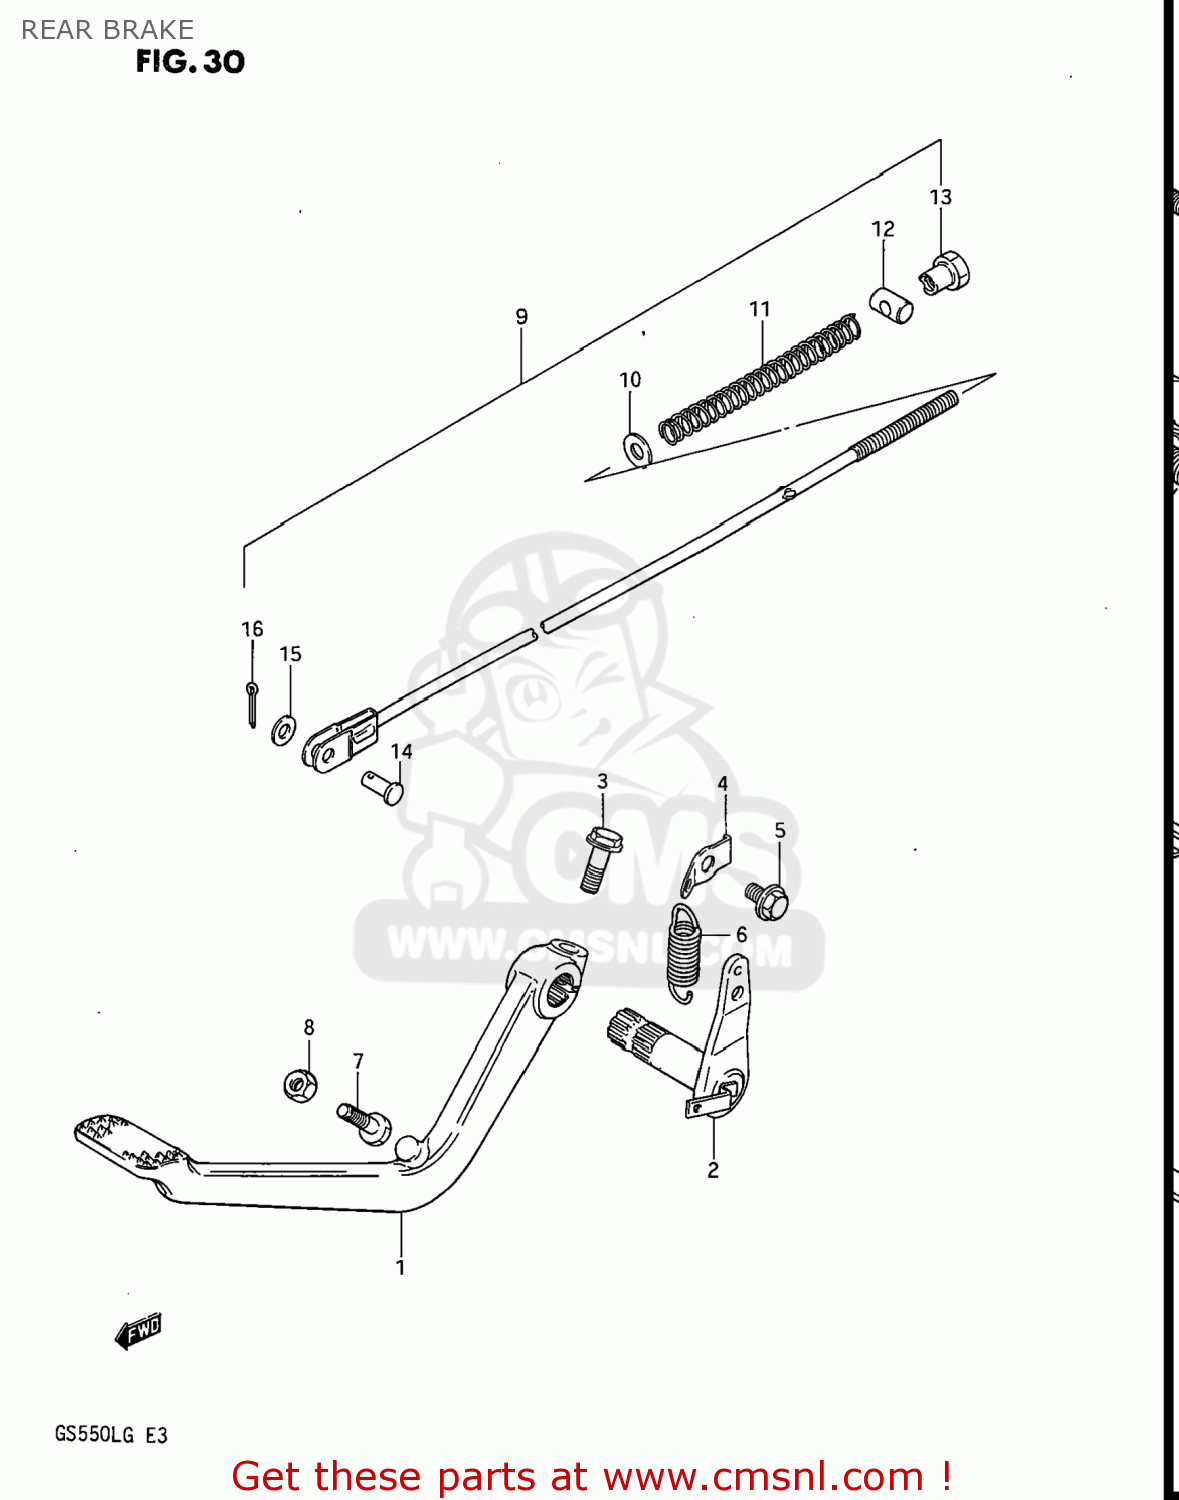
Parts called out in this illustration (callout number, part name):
1	PEDAL,BRAKE
2	ARM,BRAKE PEDAL
3	BOLT
4	PLATE.SPRING
5	BOLT
6	SPRING
7	BOLT
8	NUT 6MM
9	ROD ASSEMBLY,REAR BRAKE
10	WASHER
11	SPRING
12	PIN
13	NUT (6MM)
14	PIN(L:13.5)
15	WASHER
16	PIN 20X20
